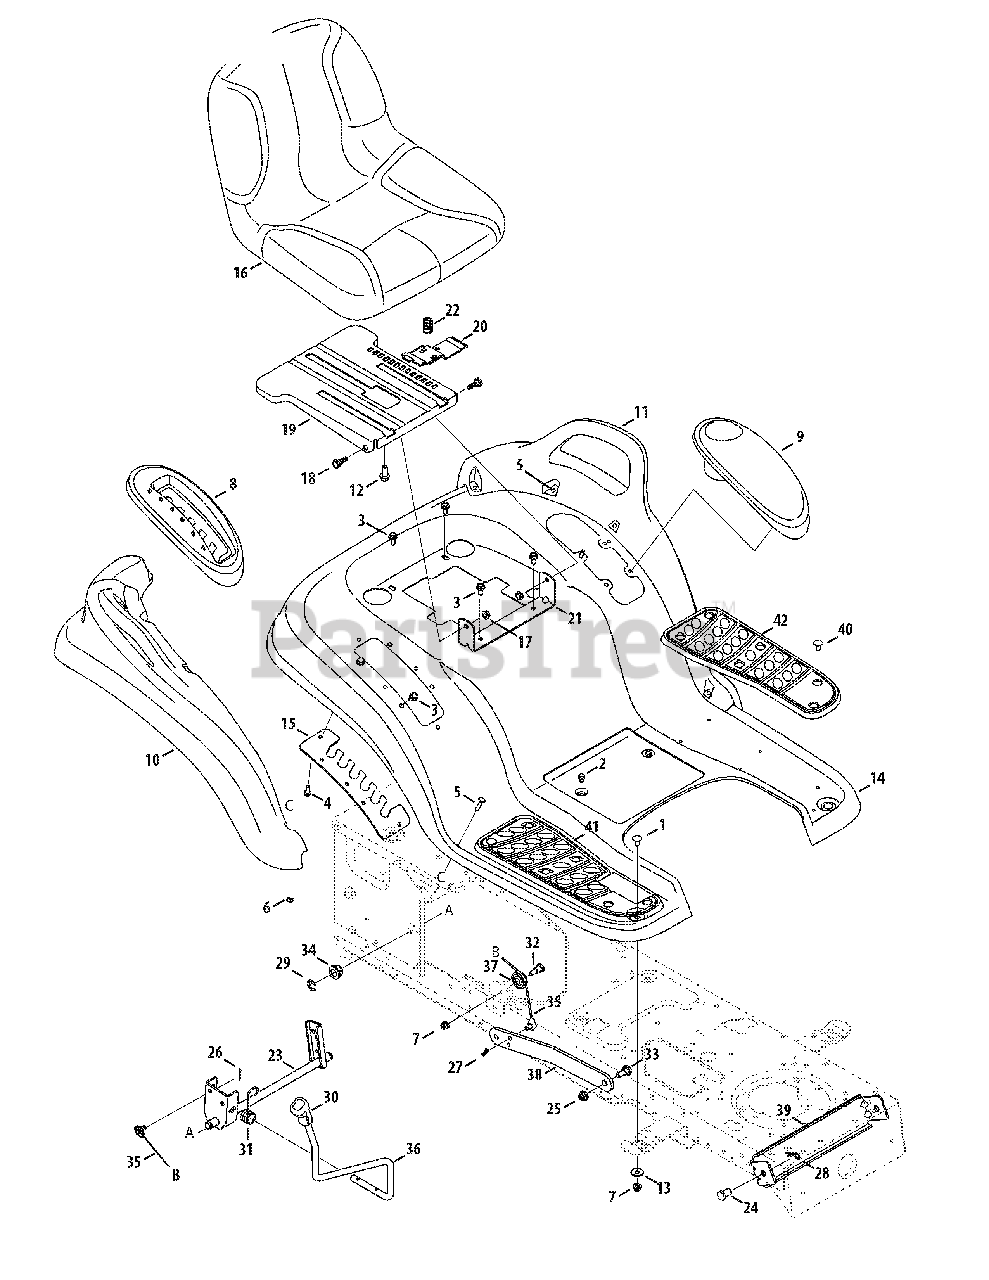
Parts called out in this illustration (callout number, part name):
1	Carriage Bolt, 5/16-18 x.750
2	Screw, 1/4-20 x.500
3	Screw, 5/16-18 x .750
4	Self-tapping Screw, 1/4-15 x.75
5	Carriage Screw 1/4-20 x 1.00
6	Sems Nut 1/4-20
7	Flange Lock Nut, 5/16-18
8	Lift Lever Cover
9	Cover w/ Cup Holder
10	RH Fender Flare
11	LH Fender Flare
12	Screw, 3/8-16 x .875
13	Flat Washer,.349 x 1.0 x.063
14	Fender 4 Sty Hydro w/ Flares
15	Lift Adjustment Bracket
16	Seat
17	Flange Lock Nut, 5/16-18
18	Shoulder Screw, .437 x .268 x 5/16-18
19	Seat Mount Bracket
20	Seat Adjustment Lever
21	Seat Pivot Bracket
22	Compression Spring, .68 x 1.065 x .055
23	Lift Shift Assembly
24	Clevis Pin, .50 dia. x .78 lg
25	Flange Lock Nut, 3/8-16
26	Cotter Pin, .072 dia. x 1.13 lg
27	Cotter Pin, 3/32 x 1.00
28	Cotter Pin, .080 x 1.5625
29	E-type Ring
30	Handle Grip
31	Torsion Spring
32	Shoulder Bolt, .496 x 2.5 x 3/8-16
33	Shoulder Bolt, .500 x .270 x 3/8-16
34	Hex Flange Bearing
35	Lift Cable
36	Lift Handle
37	Roller Pulley
38	Lift Arm
39	Front Deck Rod Adjustment Bracket
41	Foot Pad, RH
42	Foot Pad, LH
